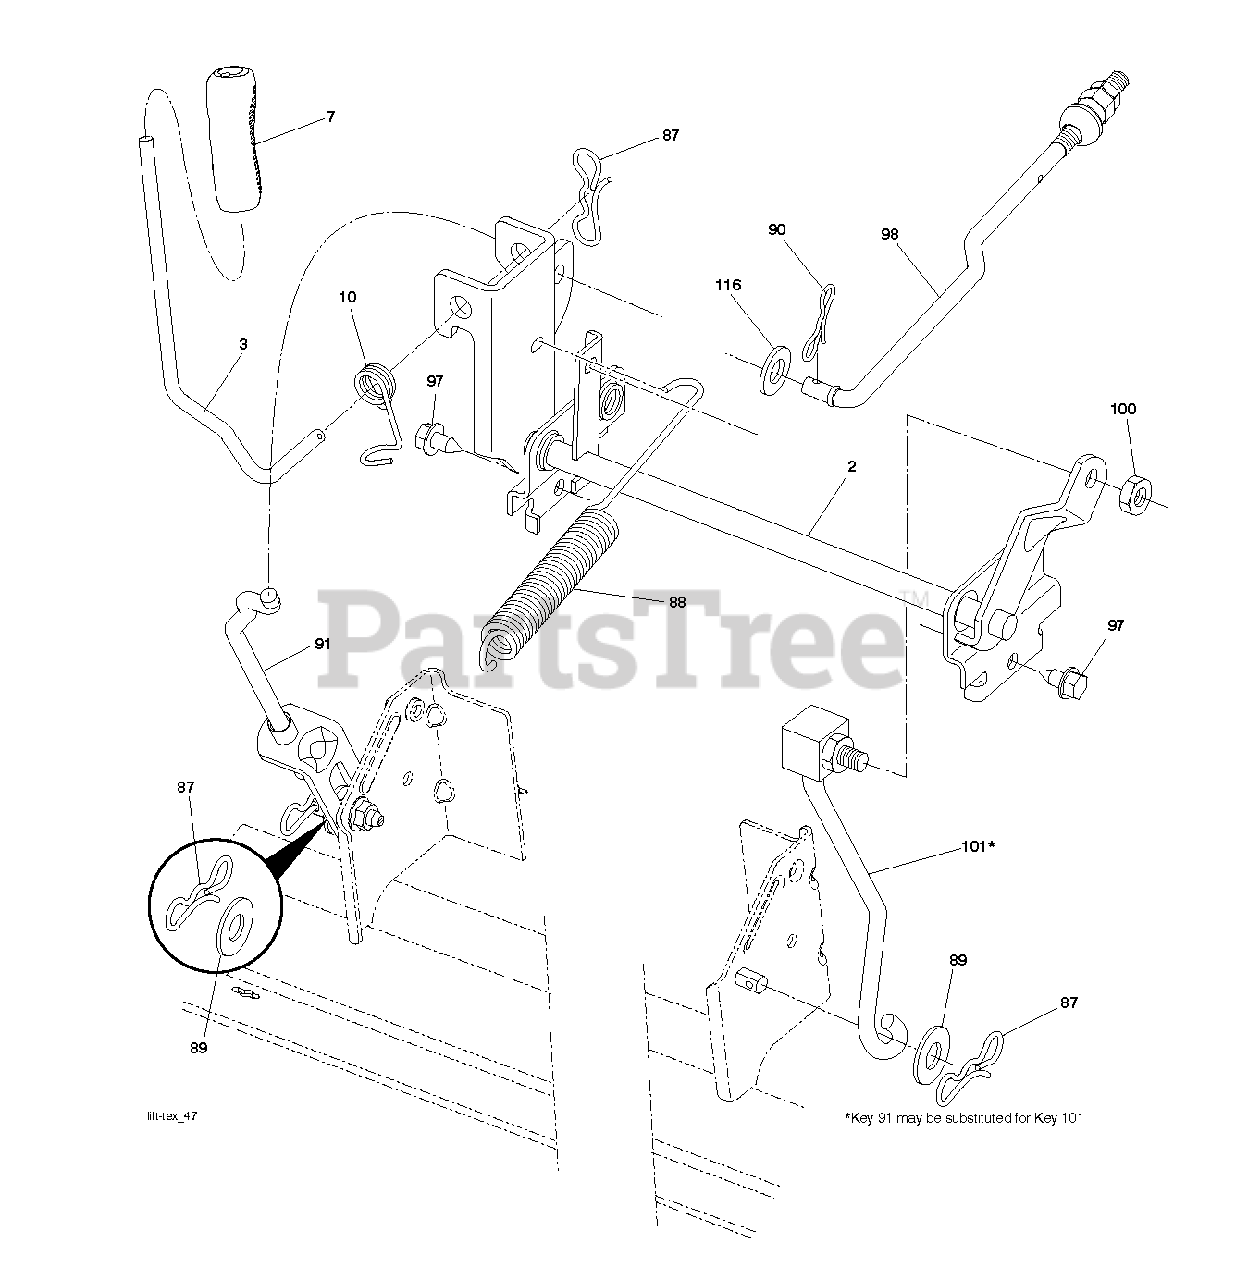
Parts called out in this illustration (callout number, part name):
2	SHAFT.ASM.CROSS.LIFT
3	LEVER.LIFT.HANDLE.LT
7	GRIP.HANDLE.LIFT.PVC.BLACK
10	SPRING.TORSION.LIFT.HANDLE
87	PIN.COTTER.7/16.BOW TI.
88	SPRING.LIFT.ASSIST
89	WASHER.CLEAR.ZINC
90	PIN.COTTER.5/16.BOW TI
91	LINK.ASM.LIFT.REAR
97	SCREW, 3/8-16X3/4
98	LINK.ASM.SUSP.FRONT.MW
100	LOCKNUT
101	LINK.ASM.LIFT.FIXE.38/42/46"
